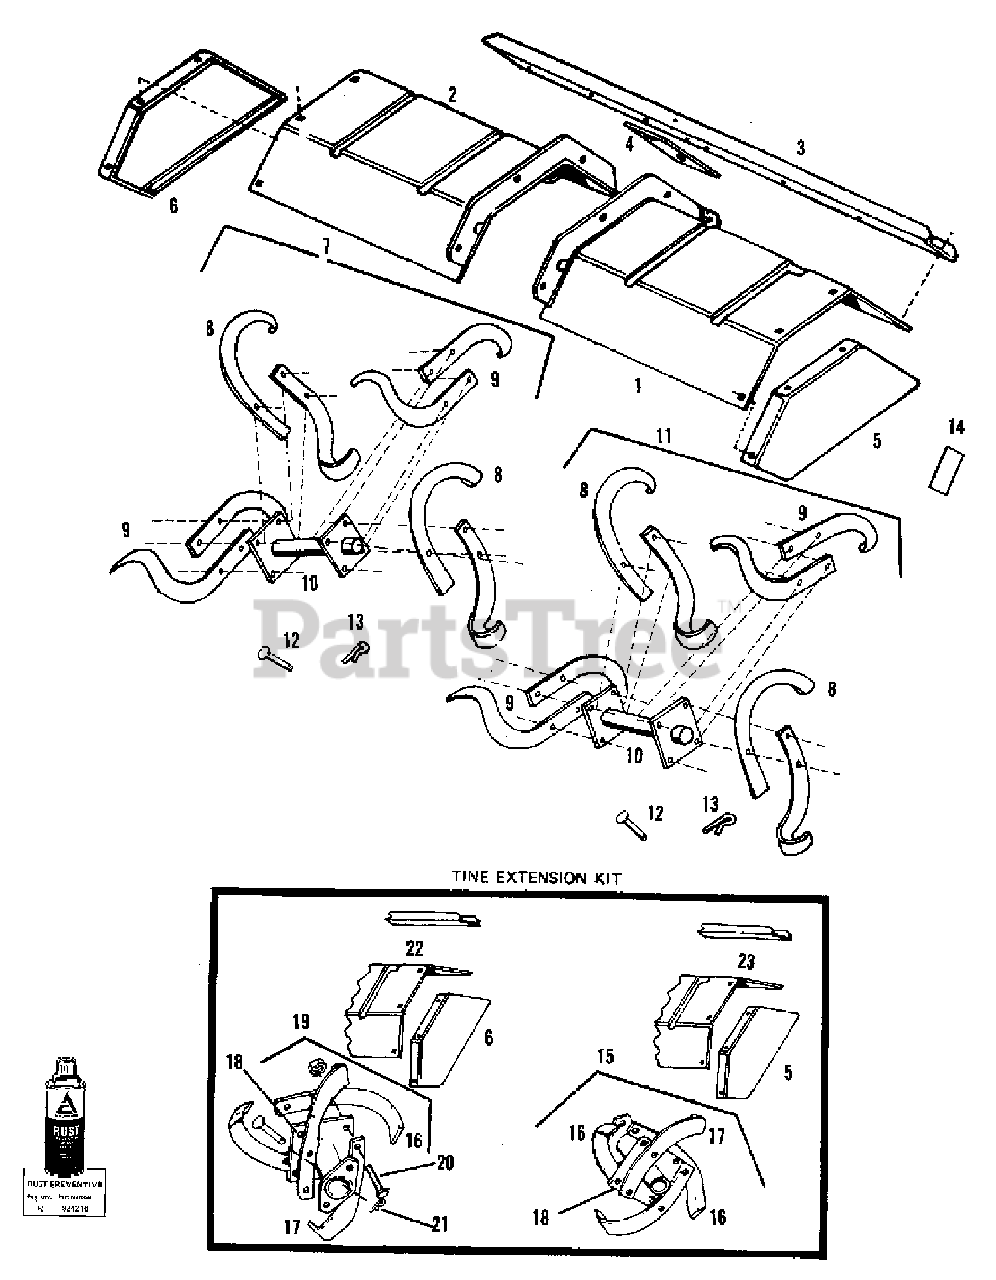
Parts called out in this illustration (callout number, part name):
1	DELECTOR ASSEMBLY, L.H.
1	CAPSCREW, 3/8NC x 1
1	CAPSCREW, 3/8NC x 5/8
1	LOCKWASHER, 3/8
2	DELFLECTOR ASSEMBLY, R.H.
2	CAPSCREW, 3/8NC x 1
2	LOCKWASHER, 3/8
3	CHANNEL, Reinforcing
3	CAPSCREW, 3/8 x 7/8
3	LOCKWASHER, 3/8
3	NUT, 3/8
4	BOLT, Carriage, 5/16NC x 3/4
4	LOCKWASHER, 5/16
4	NUT, 5/16NC
5	END, L.H. Plate Deflector
6	END, R.H.
6	BOLT, Carriage, 5/16nc X 1/2
6	LOCKWASHER, 5/16
6	NUT, 5/16NC
7	BLADE ASSEMBLY, R.H. Inner Tine
8	BLADE, L.H. Tine
9	BLADE, R.H. Tine
9	CAPSCREW, 7/16NF x 1-1/2
9	NUT, 7/16NF
10	HUB & PLATE ASSEMBLY
11	BLADE ASSEMBLY, L.H. Inner Tine (See TPG)
12	PIN, Line Shaft
13	PIN, 1/8 x 3/4, Cotter
14	DECAL, Safety
15	*BLADE ASSEMBLY, L.H.
16	*TINE, Blade, L.H.
17	*TINE, Blade, R.H.
17	*CAPSCREW, 7/16NF x 1-1/4
17	*NUT, 7/16NF, Centerlock
18	*PLATE ASSEMBLY, Tine Extension
19	*BLADE ASSEMBLY, R.H.
21	*CLIP, Spring
22	*DEFLECTOR, Ext. R.H.
23	*DEFLECTOR, Ext. L.H.
23	*BOLT, 5/16NC x 3/4, Carriage
23	*LOCKWASHER, 5/16
23	*NUT, 5/16
